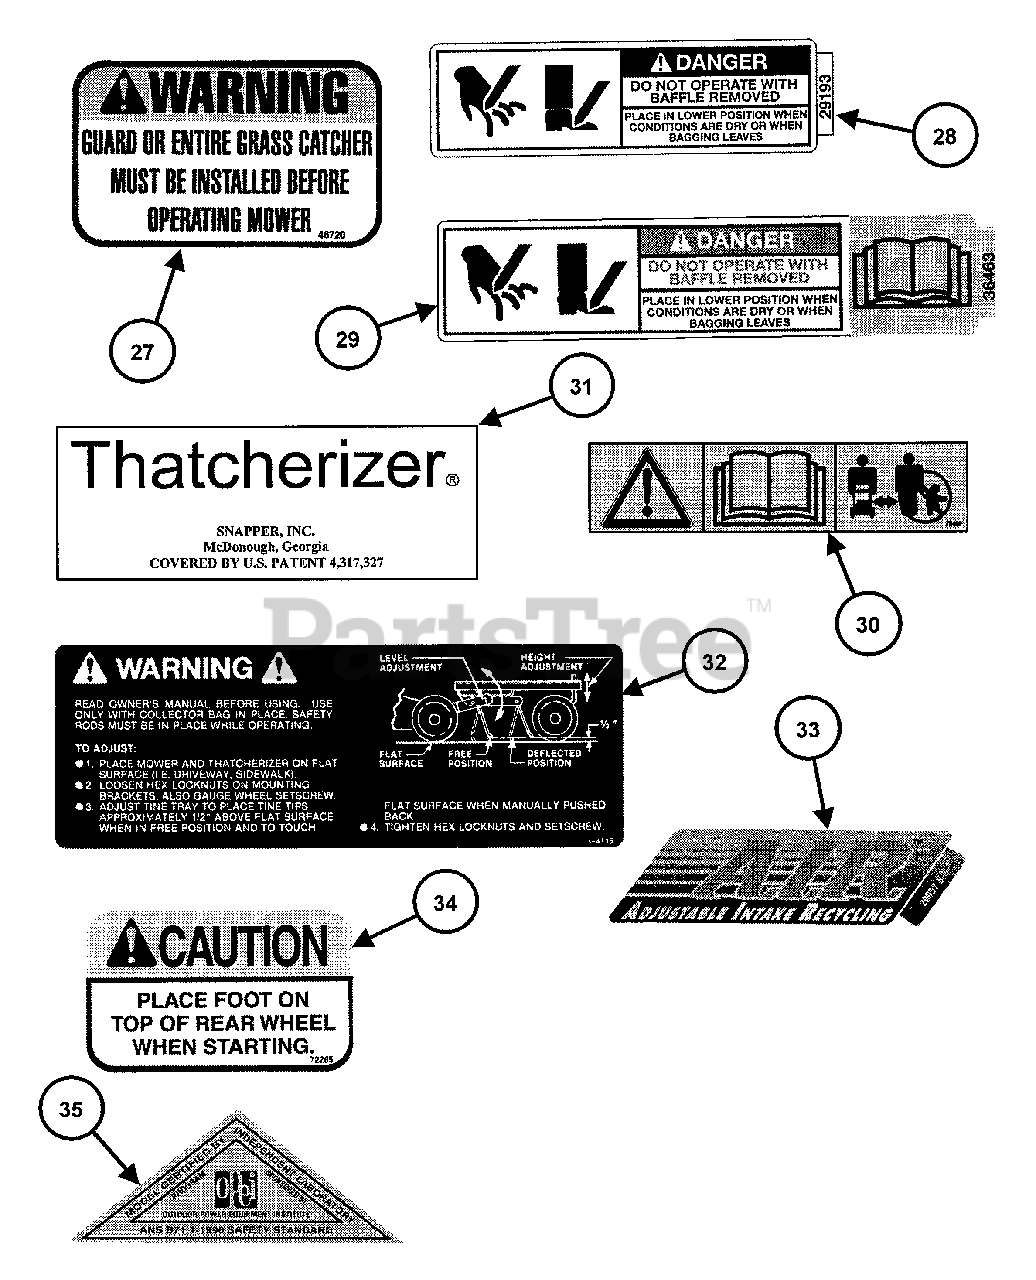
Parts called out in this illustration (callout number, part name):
27	DECAL, Warning Chute/Deflector
28	DECAL, Front Baffle
29	DECAL, Front Baffle
30	DECAL, Caution, Symbols
31	DECAL, Thatcherizer
32	DECAL, Warning Thatcherizer
33	DECAL, Medallion (Deck)
34	DECAL, Stabilization
35	DECAL, OPEI
